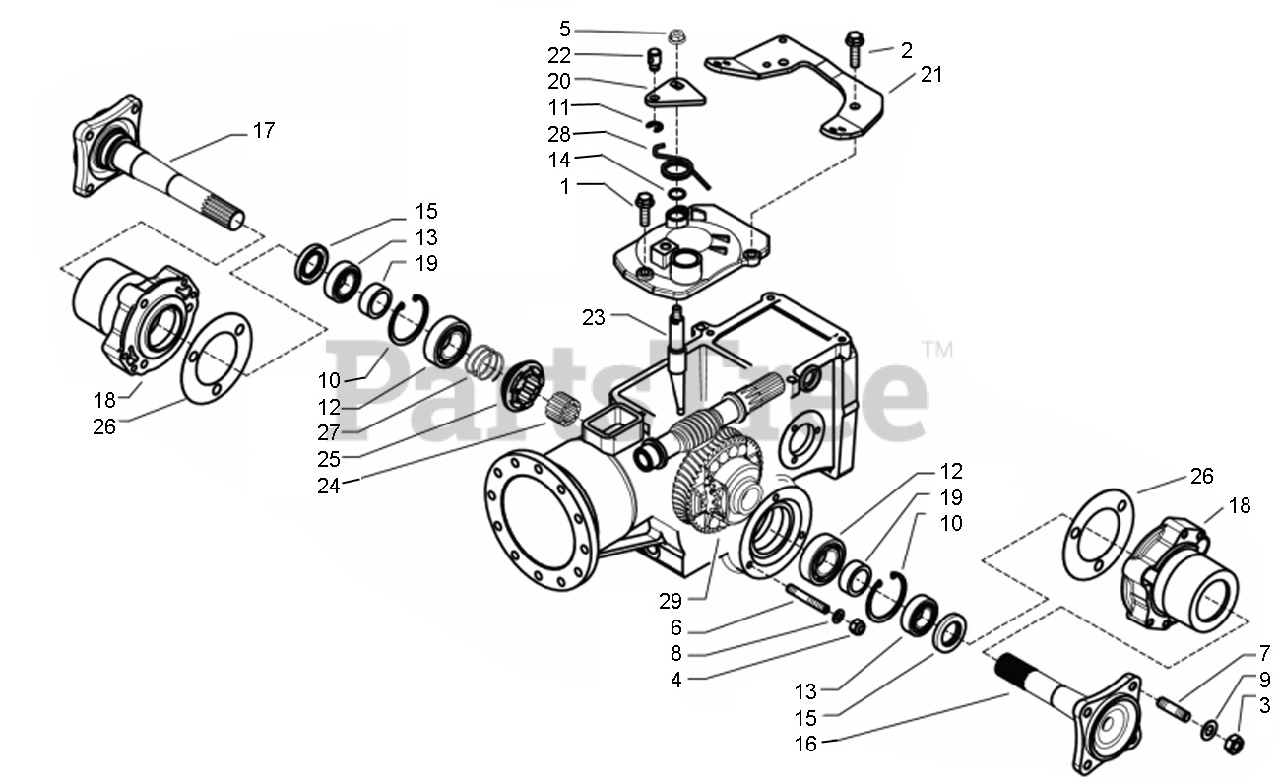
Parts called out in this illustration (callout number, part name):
1	SCREW TE C/F M8X25
2	SCREW TE C/F M8X30
3	NUT M10
4	SELFLOCK NUT M8
5	SELFLOCK NUT M8
6	STUD BOLT M8X46X20X12
7	STUD BOLT M10X40X24X12
8	SPRING WASHER 8,4
9	SPRING WASHER 10,5
10	SEEGER RING I 47
11	SEEGER RING E 6
12	BEARING
13	BEARING
14	O-RING 2056 (14,00X1,78)
15	OIL SEAL
16	AXLE SHAFT
17	AXLE SHAFT
20	LEVER
24	SPACER
25	COUPLING
26	GASKET
27	SPRING
28	SPRING
29	DIFFERENTIAL GEAR
